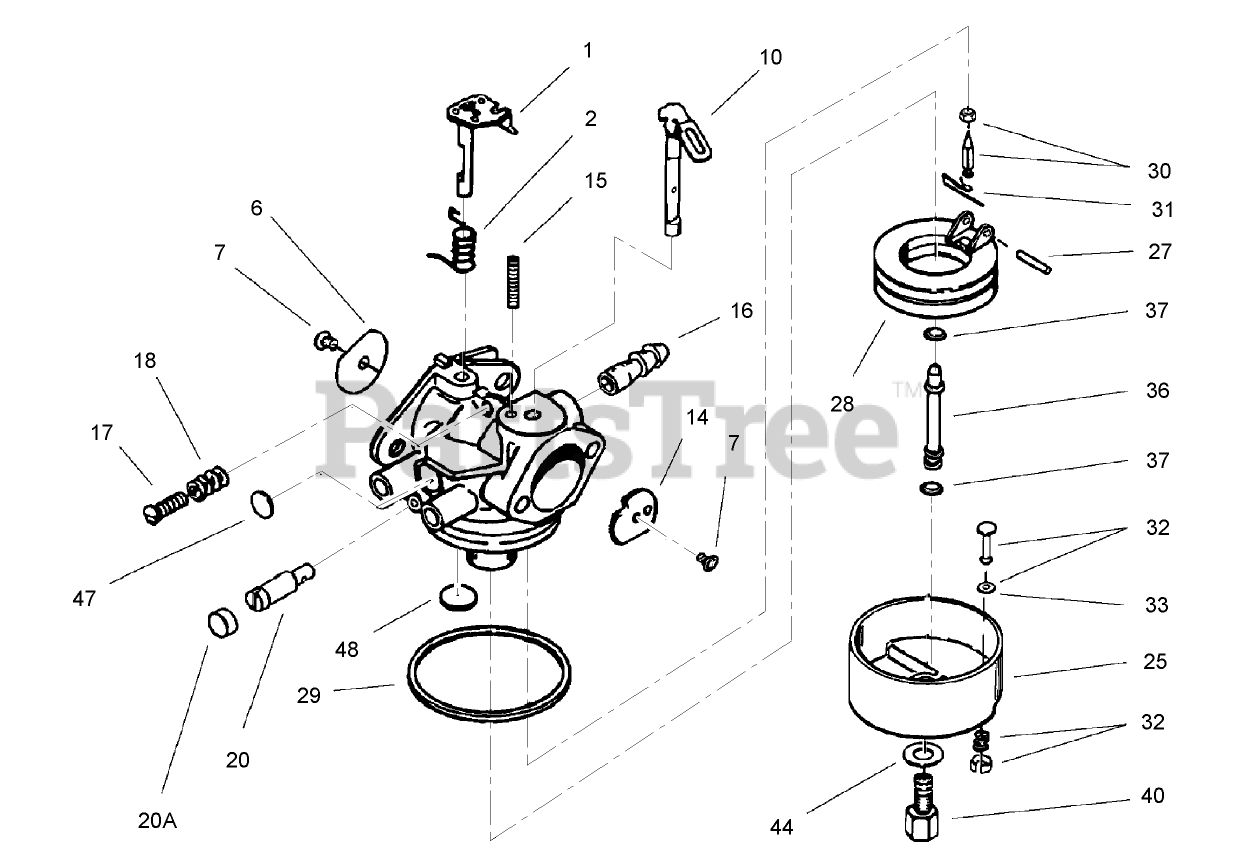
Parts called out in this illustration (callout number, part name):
1	Throttle Shaft and Lever ASM
2	Spring-Return, Throttle
6	Shutter-Throttle
7	Screw-Shutter
10	Choke Shaft and Lever ASM
14	Shutter-Choke
15	Spring-Positioning, Choke
16	Fitting-Fuel
17	Screw-Throttle Crack Screw / Idle Speed
18	Spring-Tension
20	Screw-Restrictor, Idle
20A	Cap-Screw, Idle Restrictor
25	Float Bowl Asm. (Incl. Ref. # 32, 33)
27	Shaft-Float
28	Float
29	O Ring-Bowl, Float
30	Inlet Needle, Seat Clip Assy. (Incl. No. 13)
31	Clip-Spring
32	Bowl Drain ASM
33	Gasket-Plunger, Drain
36	Tube-Nozzle, Main
37	O-Ring
40	Nut-High Speed, Bowl
44	Washer-Bowl Nut
47	Plug-Welch, Idle Mixture Well
48	Plug-Welch, Atmospheric Vent
